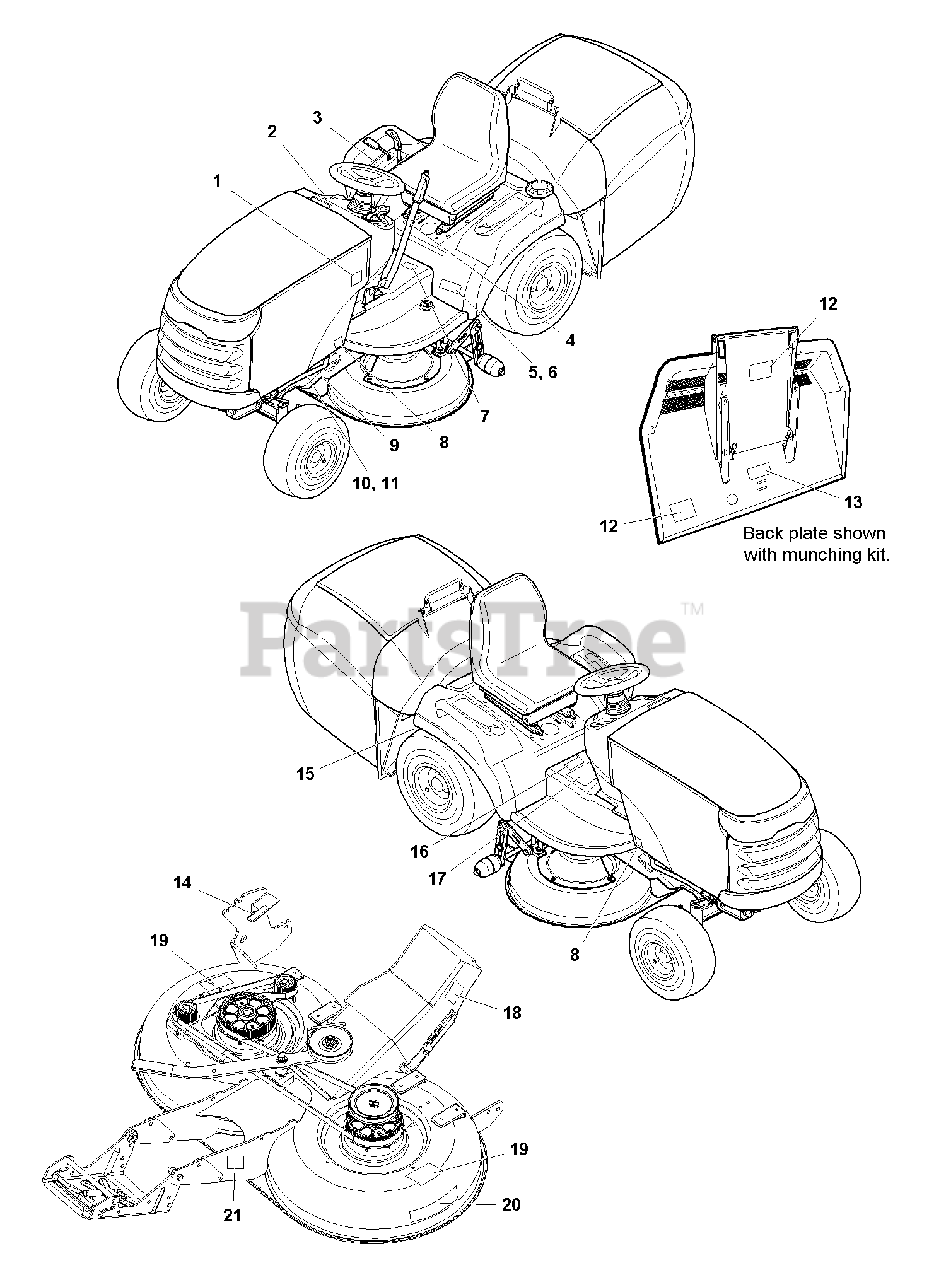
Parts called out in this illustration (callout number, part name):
1	DECAL, Belt & Blade
2	DECAL, Ignition Switch
3	DECAL, Crusie / Lift, 18HP
4	DECAL, Hopper Lever
5	DECAL, 16HP
6	DECAL, 18HP
7	DECAL, Hopper Pedal
8	DECAL, Protective, Clear
9	DECAL, Patent
10	DECAL, Decible Power Mass, Export Only, (Not Serviced)
11	DECAL, Serial Number, Tractor, (Not Serviced)
12	DECAL, Danger Operating W/O Catcher
13	DECAL, Drawbar Max Load
14	DECAL, Height Of Cut
15	DECAL, Transmission Release Valve
16	DECAL, Danger Catcher Open
17	DECAL, Warning/Danger, Tunnel
17	DECAL, Warning/Danger Icons, Tunnel, Export
18	DECAL, Danger, Discharge Tube
19	DECAL, Danger Rotating Blade
19	DECAL, Danger Rotating Blade, Export
20	DECAL, Free Floating Mower
21	DECAL, Serial Number, Mower Deck, (Not Serviced)
